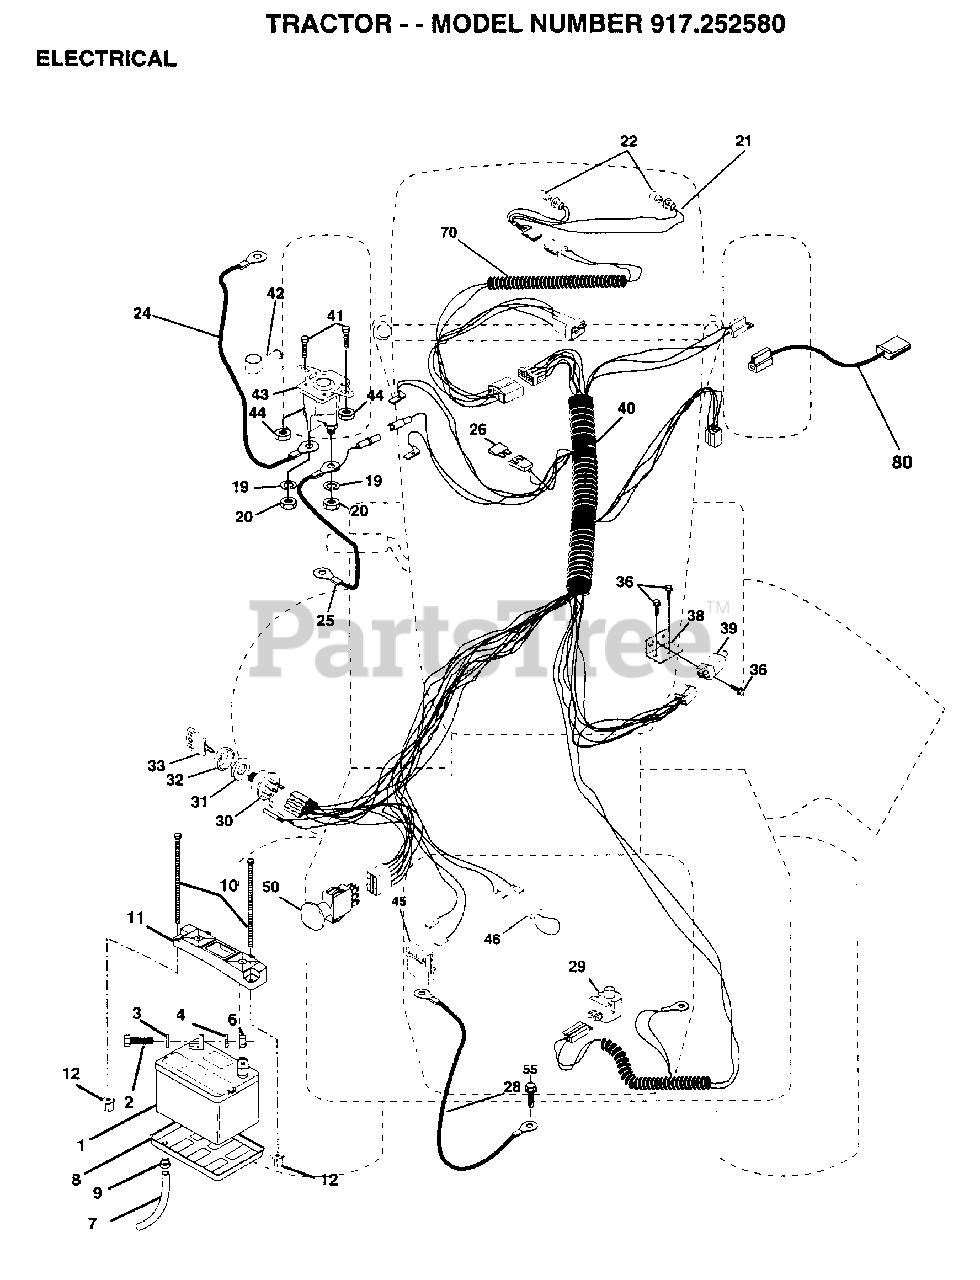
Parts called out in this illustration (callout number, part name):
2	BOLT LT
7	"DRAIN TU T, BATT"
8	"TRAY T, BATTERY"
9	HOSE CLAMP T
20	NUT
21	HARNESS.ASM.HDLIG
22	HEADLAMP BULB
24	"CABLE T, BATTERY"
25	CABLE.6GA.22W/16W
26	FUSE HYT
28	CABLE.GRND.6GA.21
29	SWITCH SEAT
30	SWITCH IGN 4POS
31	NUT IGNITION
32	COVER KEY SWITCH
33	KEY MOLDED T
38	BRACKET SWITCH IN
39	SWITCH INTERLOCKT
41	BOLT.HX.1/4-20
44	NUT
46	PROTECTION LOOP
55	SCREW LT
70	HARNESS.ENG.KOHL
80	HARNESS.CLUT.EVX.
